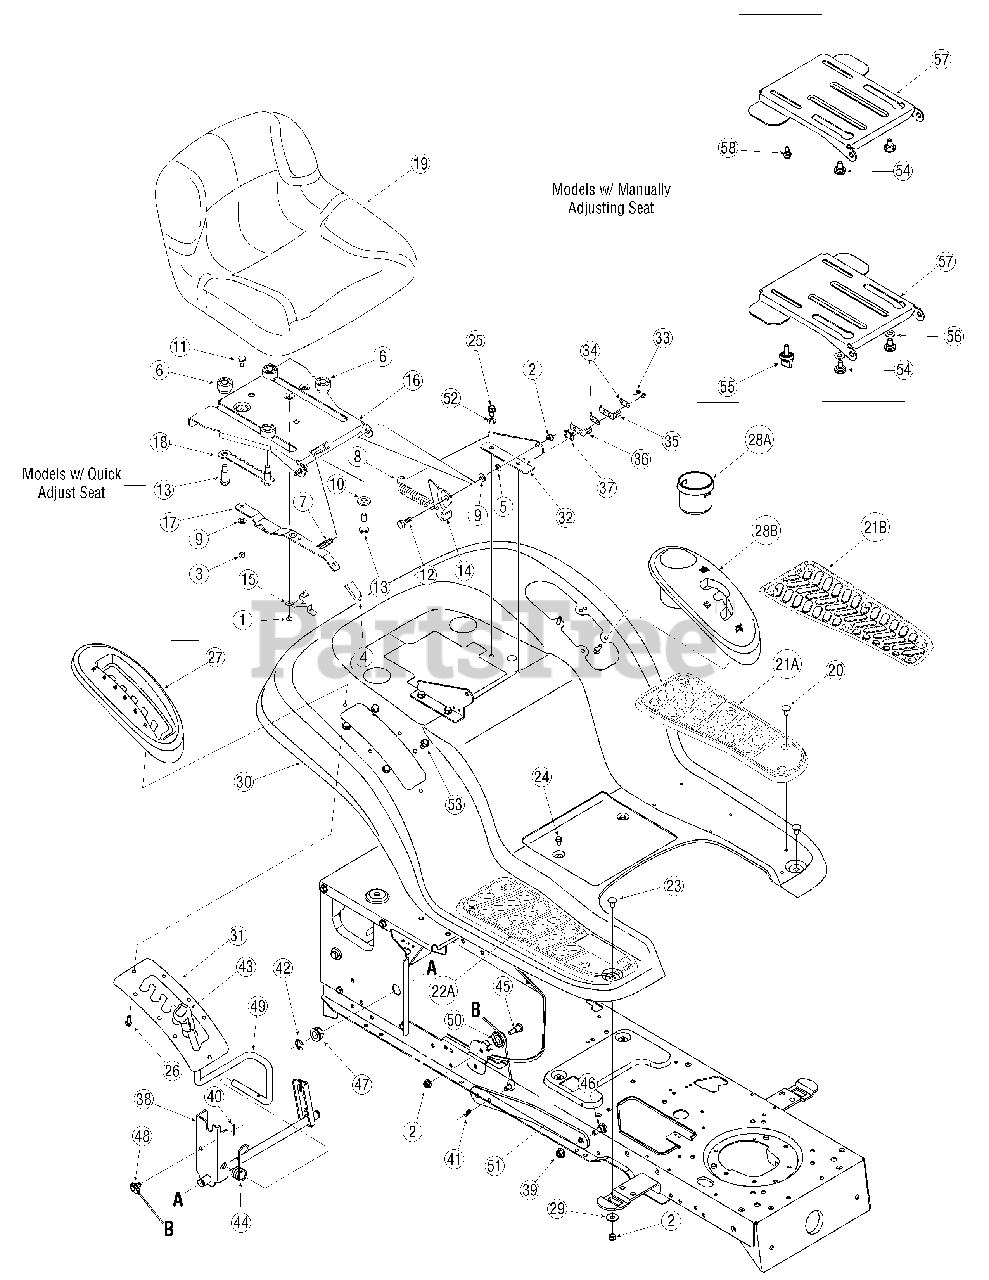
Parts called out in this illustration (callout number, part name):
1	Screw, #10-16 x.375 (if equipped)
2	Nut, Flange Lock, 5/16-18, GrF
3	Nut, Flange Lock, 1/4-20 (if equipped)
4	Seat Adjuster Grip (if equipped)
5	Nut, Speed,.3125 ID (if equipped)
6	Spacer (if equipped)
7	Compression Spring,.41 x 1.5 (if equipped)
8	Spring, Extension,.84 Dia. x 4.6
9	Wash, Flat,.344 x.688 x.065 (if equipped)
10	Wash, Flat,.531x 1.062 x.134 (if equipped)
11	Screw, Shld, .340 x.285, 1/4-20 (if equipped)
12	Screw, Shoulder,.437 x.268
13	Screw, Should,.50 x.925, 3/8-16 (if equipped)
14	Seat Bracket, Lift
15	Seat Stop (if equipped)
18	Seat Adjustment Selector (if equipped)
19	Medium Back Seat
20	Ratchet Clip
21A	LH Foot Pad, Rubber
21B	LH Foot Pad, Rubber
22A	RH Foot Pad,Rubber
23	Bolt, Carriage, 5/16-18,.75, Gr1
24	Screw, 1/4-20, 0.500
25	Screw, 5/16-18, 0.625
26	Screw, 1/4-15, 0.750 (if equipped)
27	Cover, Lift Lever (if equipped)
28B	Cover, w/ Cup Holder
29	Washer, Flat,.344 x 1.0 x.063
33	Screw, #8-18 x.50
34	Plate, Insulator
35	Spring Switch, Outer
36	Spring Switch, Inner
37	Plate, Insulator Boss
38	Shaft Assembly, Lift Service Kit
39	Nut, Flange Lock, 3/8-16,GrF
40	Pin, Cotter,.072 Dia. X 1.13
41	Pin, Cotter, 3/32, 1.0
42	Ring, E Type,.625 Dia.
43	Grip, Handle, 1/2
44	Spring, Torsion
45	Screw, 5/16-18 x.620 Gr2
46	Scr.,Shldr, .625 x.165,(42" Deck)
46	Screw, Shld,.50 x.27, (46" Deck)
47	Bearing, Hex Flange
48	Cable, Lift, 16.16
50	Pulley, Roller
52	Lock Washer, 5/16
53	Scr5/16-18 x.750 (Model X605H)
53	Screw, 5/16-12
54	Shoulder Screw (if equipped)
55	Knob, 3/8-16 (if equipped)
56	Flat Washer, .406 x . 875 x .059 (if equipped)
58	Hex Head Washer Screw, 3/8-16 (if equipped)
